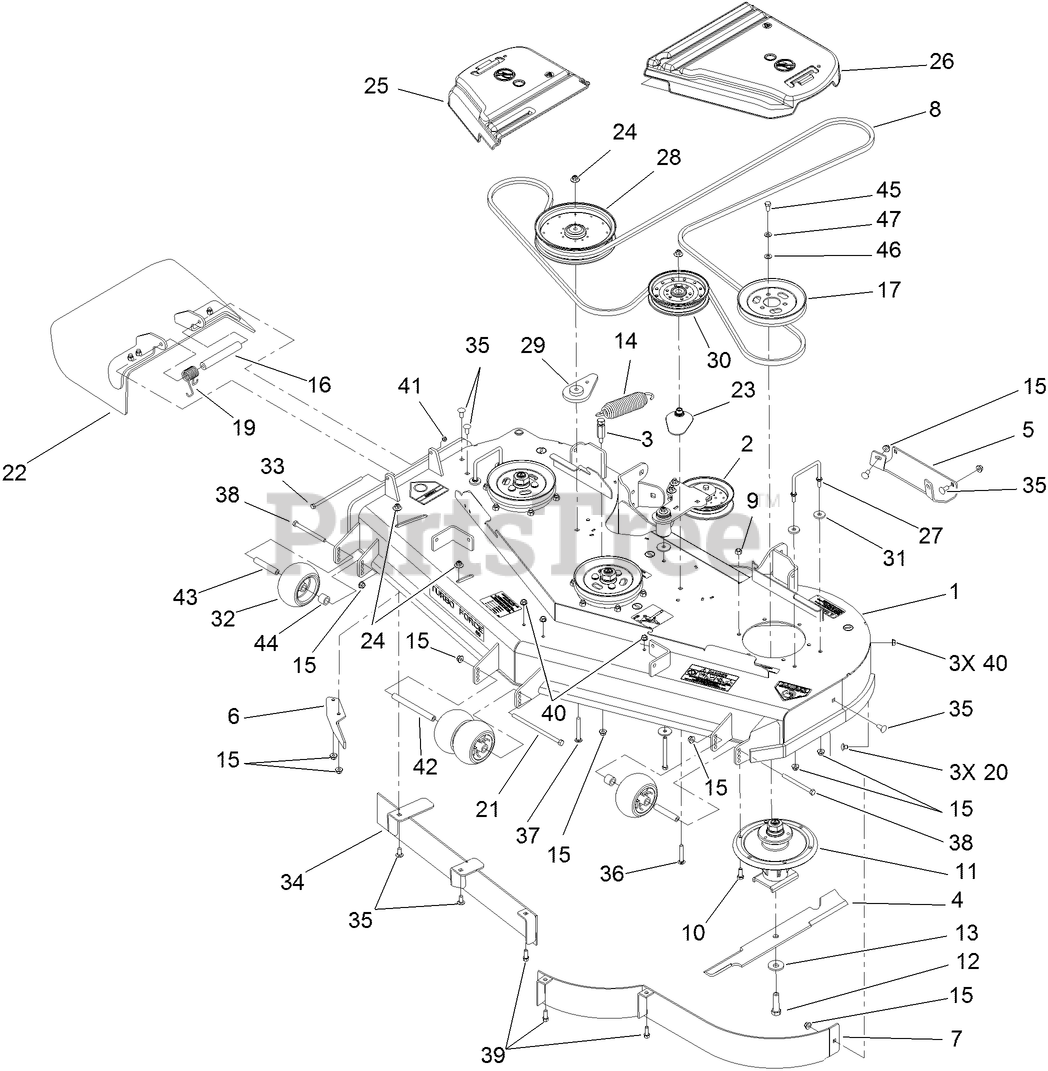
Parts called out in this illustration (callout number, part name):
1	DECK DECAL ASM
2	IDLER ARM ASM
3	ANCHOR-SPRING, TALL
4	BLADE-HI FLOW
5	Plate-Skid
6	BAFFLE-DISCHARGE
8	BELT-V
9	NUT-LOCK, NI
10	SCREW-HH
11	SPINDLE ASM
12	SCREW-BLADE
13	Washer-Blade Bolt, Heavy
14	EXTENSION-SPRING
15	NUT-HF, NI
16	SPACER
17	Pulley
19	SPRING-TORSION
20	SCREW-CARR
21	SCREW-HH
22	RUBBER DEFLECTOR ASM
23	SPACER-PULLEY
24	NUT-FLANGE, NI
25	COVER-BELT, RH
26	COVER-BELT, LH
27	WIREFORM-COVER
28	PULLEY-IDLER
29	SPACER-IDLER
30	PULLEY-IDLER, FLAT
31	WASHER
32	ROLLER-SCALP, ANTI
33	SCREW-HH
35	SCREW-CARR
36	BOLT-CARR, SHORT NECK
37	SCREW-CARR
38	SCREW-HH
39	SCREW-HWH
40	NUT-HHF, WHIZ
41	NUT-LOCK, NI
42	SPACER-WHEEL
43	TUBE-SPANNER
44	TUBE-SPACER
45	SCREW-HH
46	WASHER-FLAT
47	WASHER-BELLEVILLE
